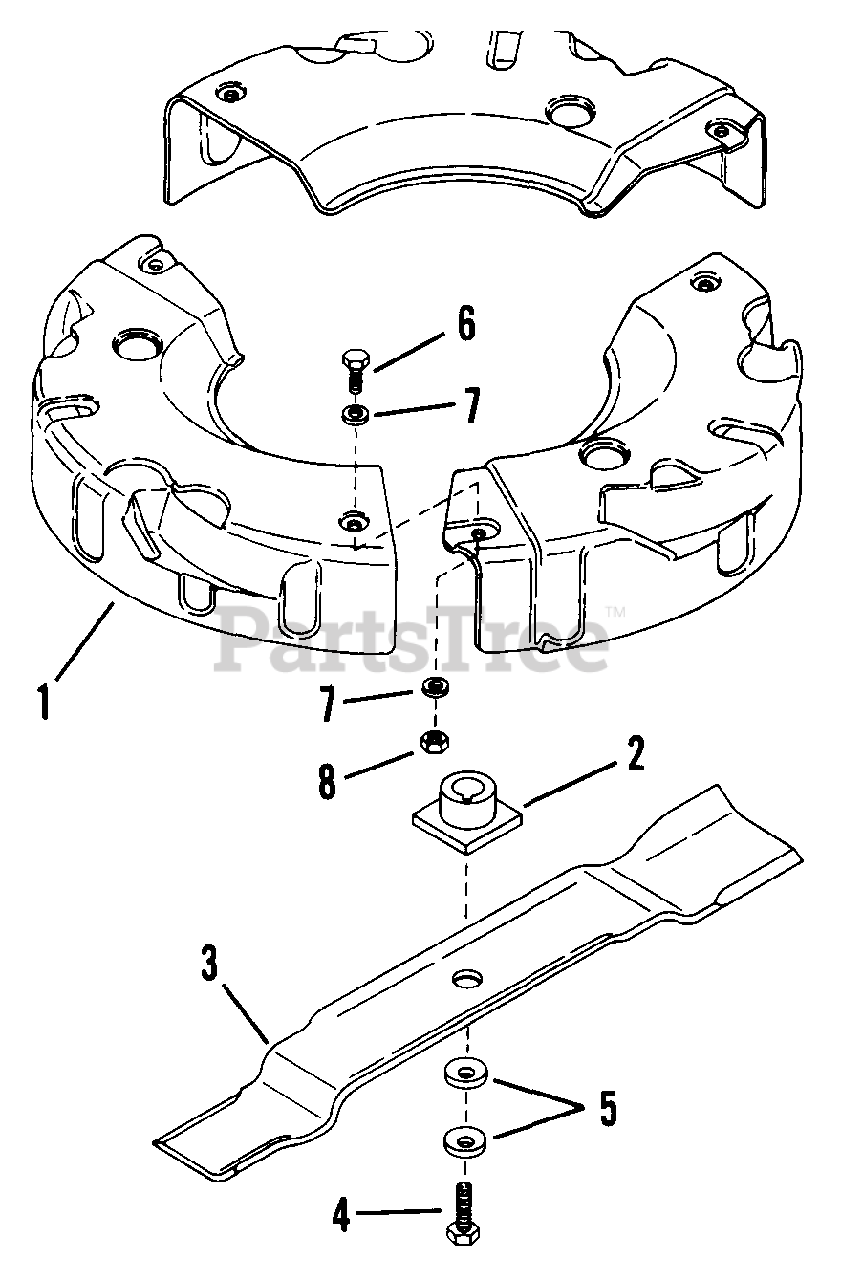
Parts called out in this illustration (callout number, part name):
2	HUB, 7/8" I.D.
3	BLADE, Mulcherizer
4	SCREW, 3/8-24 x 1 3/4" Hex Head Cap (Gr.5)
5	WASHER, Cone
6	SCREW, 1/4-28 x 5/8" Hex Head Cap (Gr.5)
7	WASHER, 1/4 Flat
8	NUT, 1/4-28 Hex Lock
